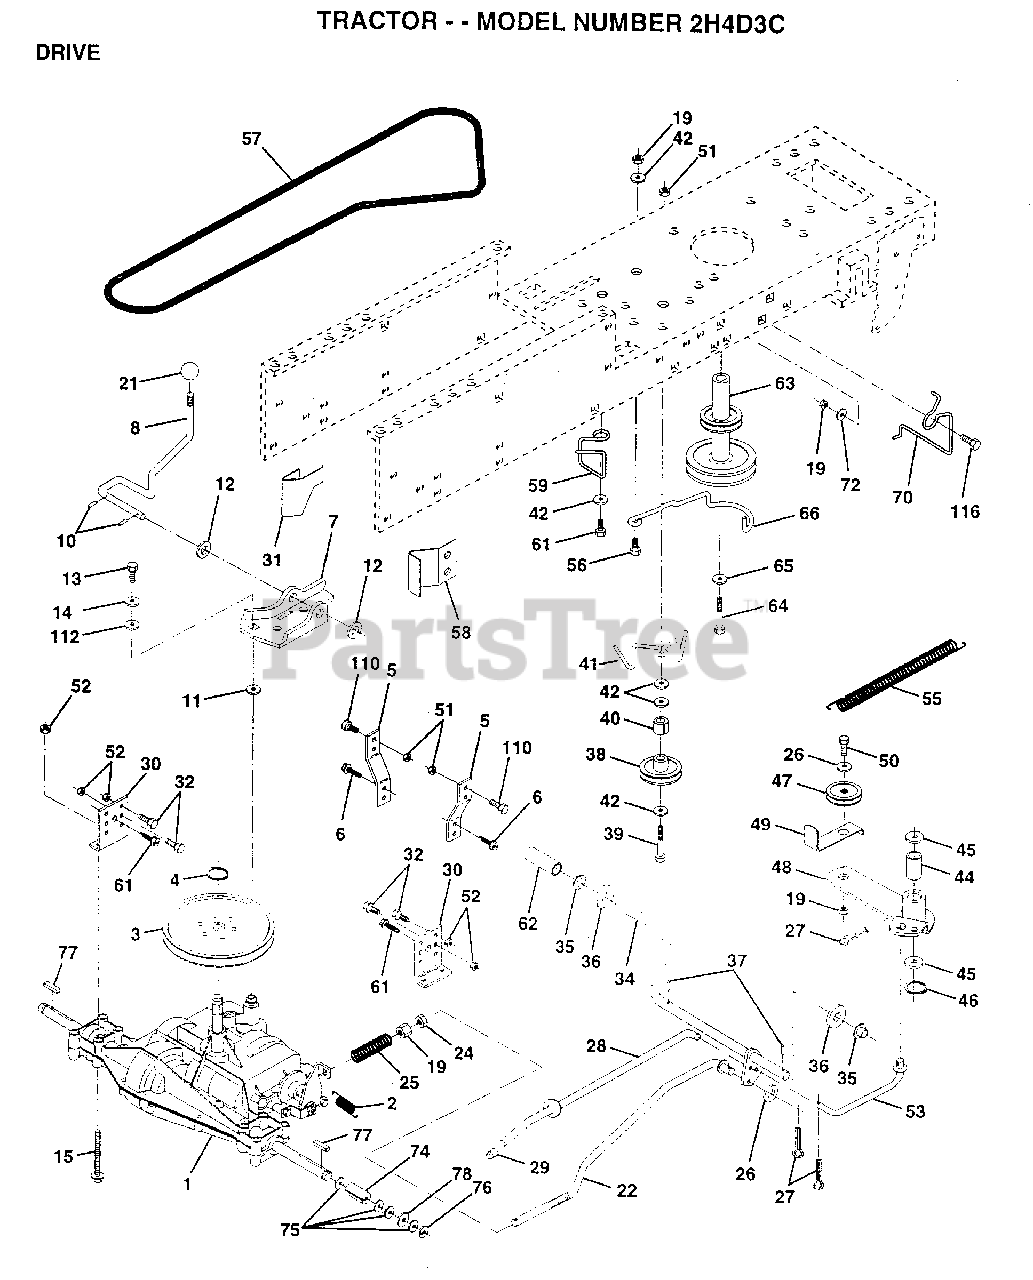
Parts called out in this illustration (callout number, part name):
2	SPRING.BRAKE.RETU
3	PULLEY TRANS
5	STRAP TORQUE
6	SCREW
8	SHIFT ROD
10	PIN COTTER 1/8
11	WASH-SHFT PLT LT
12	WASHER
13	BOLT.1/4-28.W/PAT
14	LOCKWASHER
15	BOLT.HX.FLG.5/16
19	NUT
21	KNOB T (1/2-HOLE)
22	BRAKE ROD
24	NUT
25	SPRING ROD LT
26	WASHER
27	COTTER PIN
28	ROD.BRAKE.PARK.LT
29	PLUNGER CAP T
30	TRANSAXLE MTG BKT
31	"KEEPER,BELT LH T"
32	BOLT
34	SHAFT FOOT PEDAL
35	NYLON BEARING
36	WASHER LT
38	PULLEY.IDLER.FLAT
39	BOLT
40	SPACER T
41	KEEPER BELT
42	WASHER
44	"LY, BEARING"
45	WASHER LT
46	KLIP RING
48	ARM IDLER
49	RETAIN BELT
53	"LINK, CLUTCH T"
55	"SPRING, RETURN LT"
58	"KEEPER,BELT RH T"
59	KEEPER BELT CNTSP
61	SCREW
62	PEDAL COVER T
63	PULLEY.ENGINE
64	BOLT
65	LOCKWASHER
70	KEEPER BELT ENG
72	WASHER
74	SPACER LT
75	WASHER
76	E-RING LT
77	SQUARE KEY
78	WASHER
112	WASHER LT
116	BOLT RDHD 3/8-16
